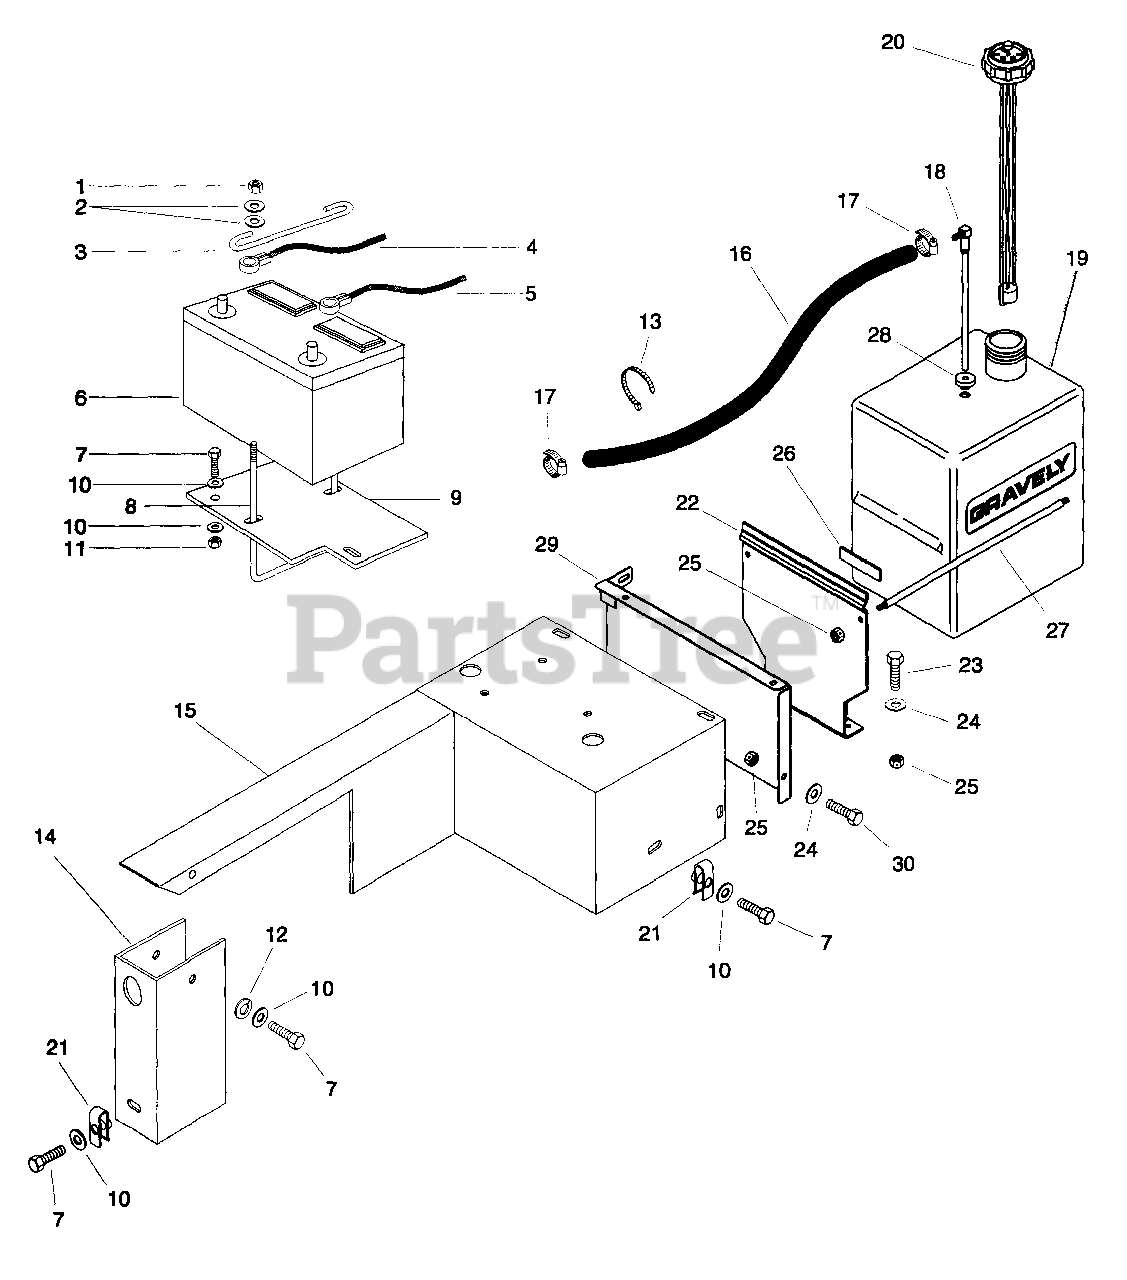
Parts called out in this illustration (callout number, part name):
1	Nut-Lk-Ctr .25-20
2	Wshr-Fl-Stl .312 x .734 x .065
3	Rod, Hold Down
4	Battery Cable
5	Ground Cable
6	Battery
7	BIt-Hex .38-16 x 1.00 Gr 5
8	Rod Battery
9	Mounting Plate
10	Wshr-Fl-Stl .438 x 1.00 x .083
11	Nut-Lk-Ctr .38-16
12	Wshr-Lock .38 x .094
13	Tie Wrap
14	Hour-Meter Mount
15	Belt Guard Weldment
16	Gas Line-Bulk 1/4" ID
17	Hose Clamp
18	Fitting, Tank
19	Tank, Fuel
20	Gauge, Fuel
21	Nut-Cage .375-16
22	Tank Bracket
23	Bit-Hex .31-18 x 1.00 Gr 5
24	Wshr-Fl-Stl .38 x .875 x .083
25	Nut-Lk-Ctr .31-18
27	Rod, Tank
28	Bushing
29	End Plate Weldment
30	Bit-Hex .31-18 x .75 Gr 5
